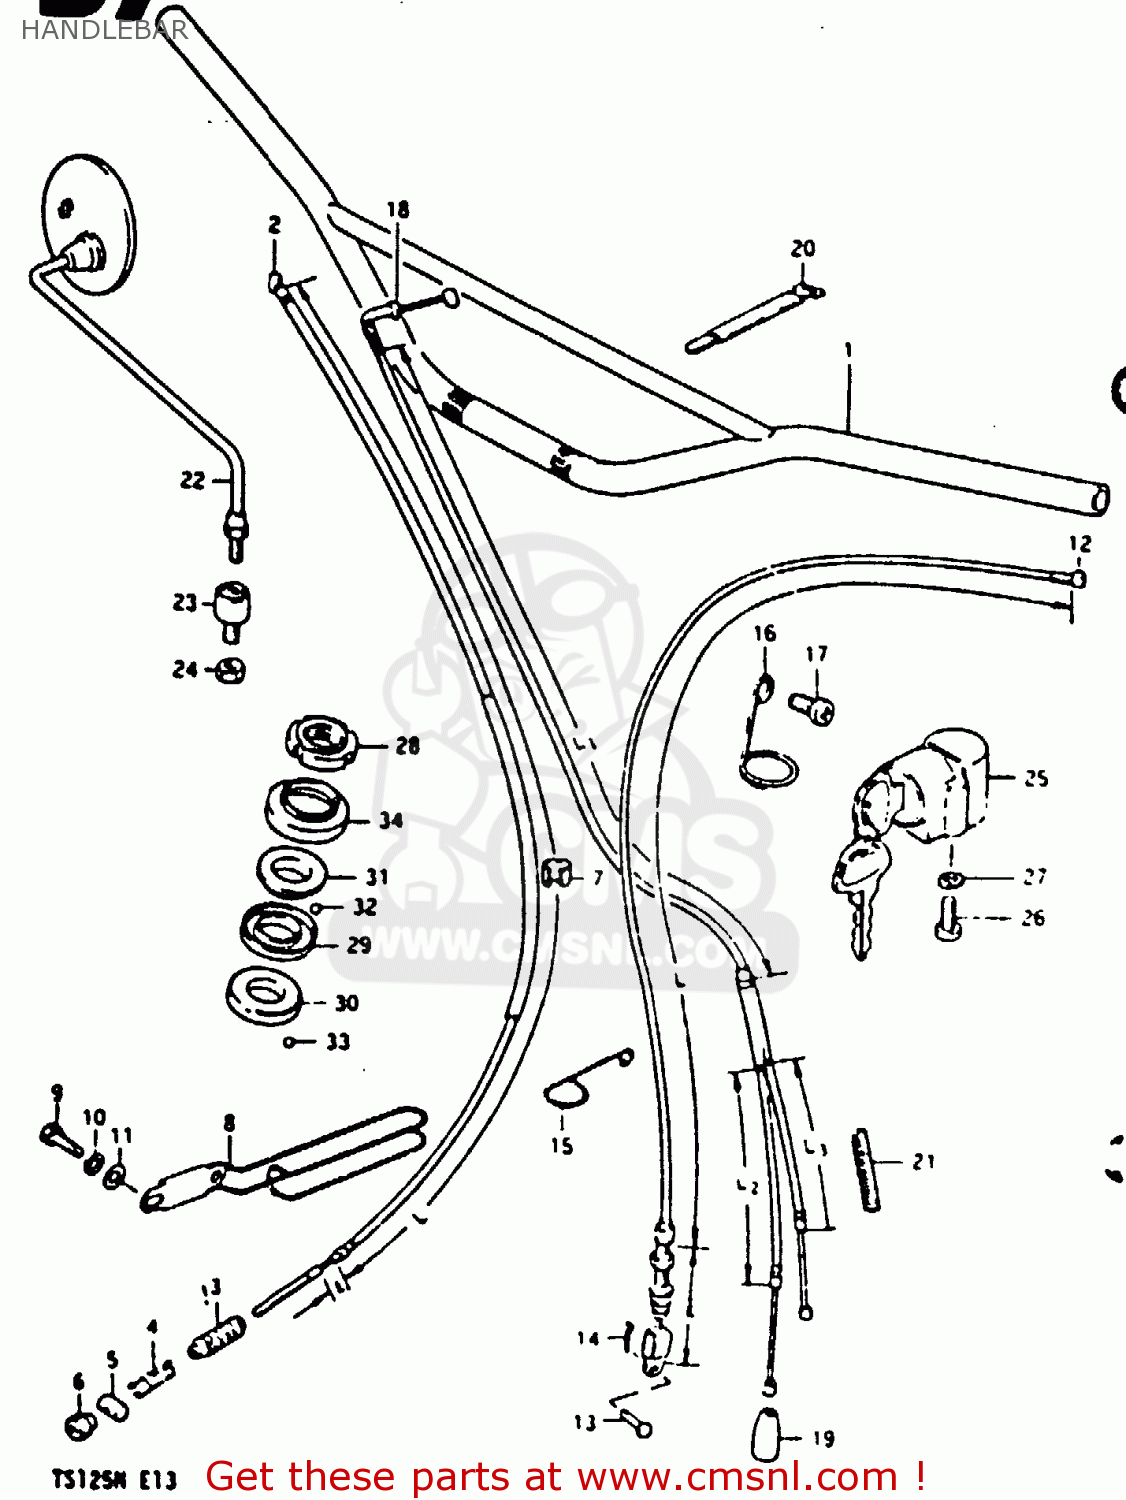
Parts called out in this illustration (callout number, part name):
1	HANDLEBAR
2	CABLE ASSEMBLY,FRONT BRAKE
3	SEAL,DUST(7X16X75)
4	SPRING
5	PIN,10X19
6	NUT
7	CLIP
8	GUIDE,CABLE
9	BOLT 8X12
10	LOCK WASHER
11	WASHER
12	CABLE ASSEMBLY,CLUTCH
13	PIN(L:15)
14	PIN
15	CLAMP
16	CLIP,TACHOMETER CABLE
17	SCREW
18	CABLE ASSEMBLY,THROTTLE
19	SEAL,DUST(7X18X30)
20	CLAMP
21	PROTECTOR,CABLE
22	23
23	CUSHION,REAR VIEW MIRROR
24	NUT
25	LOCK ASSEMBLY,STEERING
26	SCREW
27	LOCK WASHER
28	NUT,STEERING STEM(25X44X10)
29	RACE,STEERING INNER UPR
30	LACE,STEERING INNER LWR
31	RACE,STEERING OUTER UPR
32	BALL
33	BALL
34	DUST SEAL,STEERING UPR
